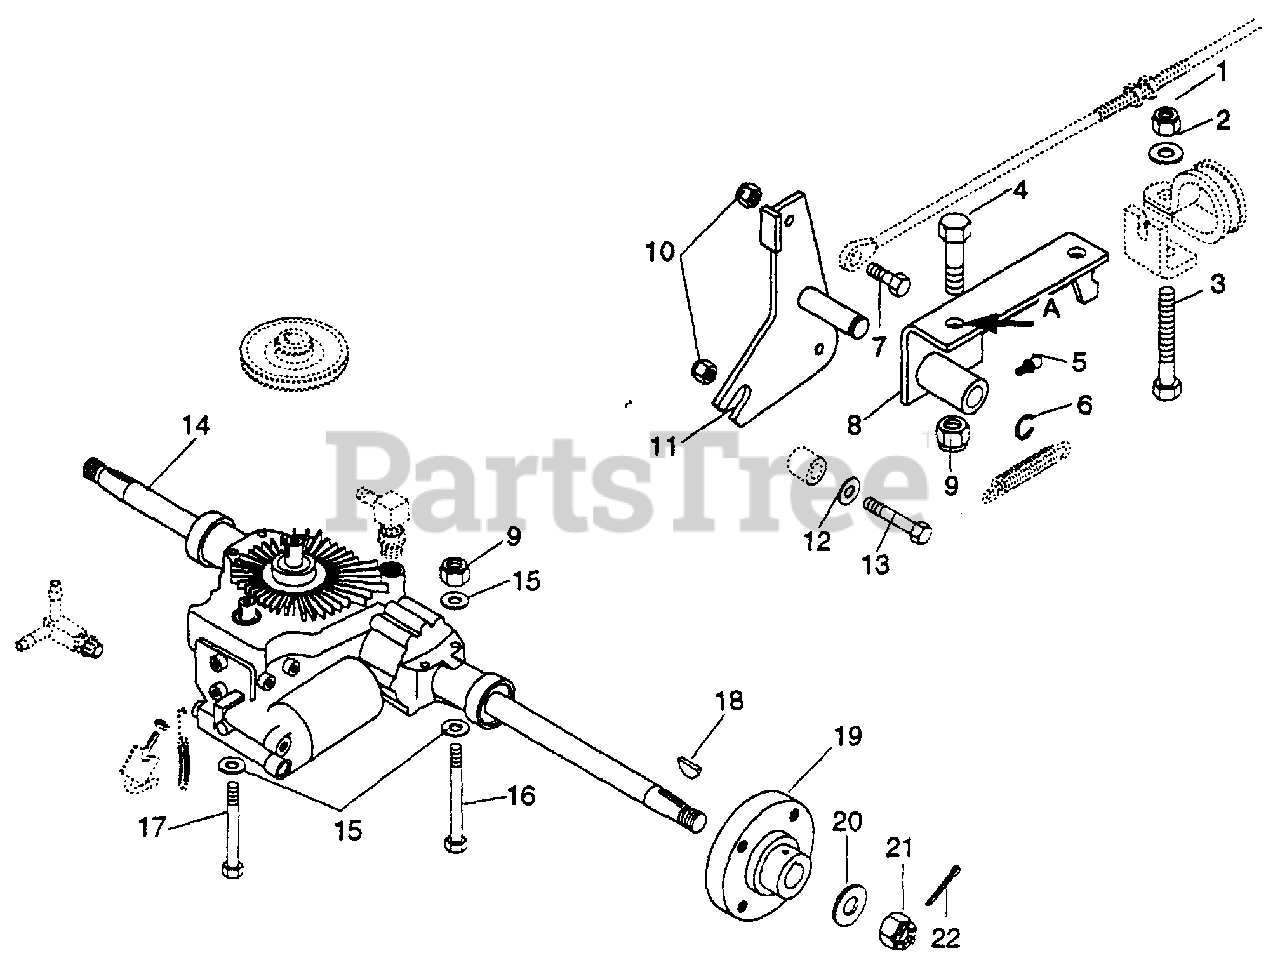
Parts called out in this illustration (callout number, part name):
1	NUT-LK-NYL .312-18 PL
2	WSHR-FL-STL .344 X .688 X .065 PL
3	BLT-HEX .31-18 X 1.00 PL GR 5
4	BLT-HEX .38-16 X 1.00 PL GR 5
5	FTG-LUBE .25-28 X .256
6	RG-RTNG-EXT .392 X .042
7	BLT-HEX .25-20 X .875
8	WLDMT, BRAKE PIVOT
9	NUT-LK-NYL .375-16 PL
10	NUT-LK-NYL .250-20 PL
11	WLDMT, BRAKE ARM
12	WSHR-FL-STL .281 X .62 X .065
13	BLT-HEX .25-20 X 1.75 GR 2
14	TRANSAXLE, HYDROSTATIC 90367
15	WSHR-FL-STL .406 X .812 X .065 PL
16	BLT-HEX .38-16 X 4.00
17	BLT-HEX .38-16 X 3.25 PL GR 5
18	KEY WDRF .25 X 1.0 X 7 SAE 15
19	HUB
20	WSHR-FL-STL .813 X 1.370 X .100
21	NUT-HEX SL .75-20
22	PIN COTR. 12 X 1.25 PL
